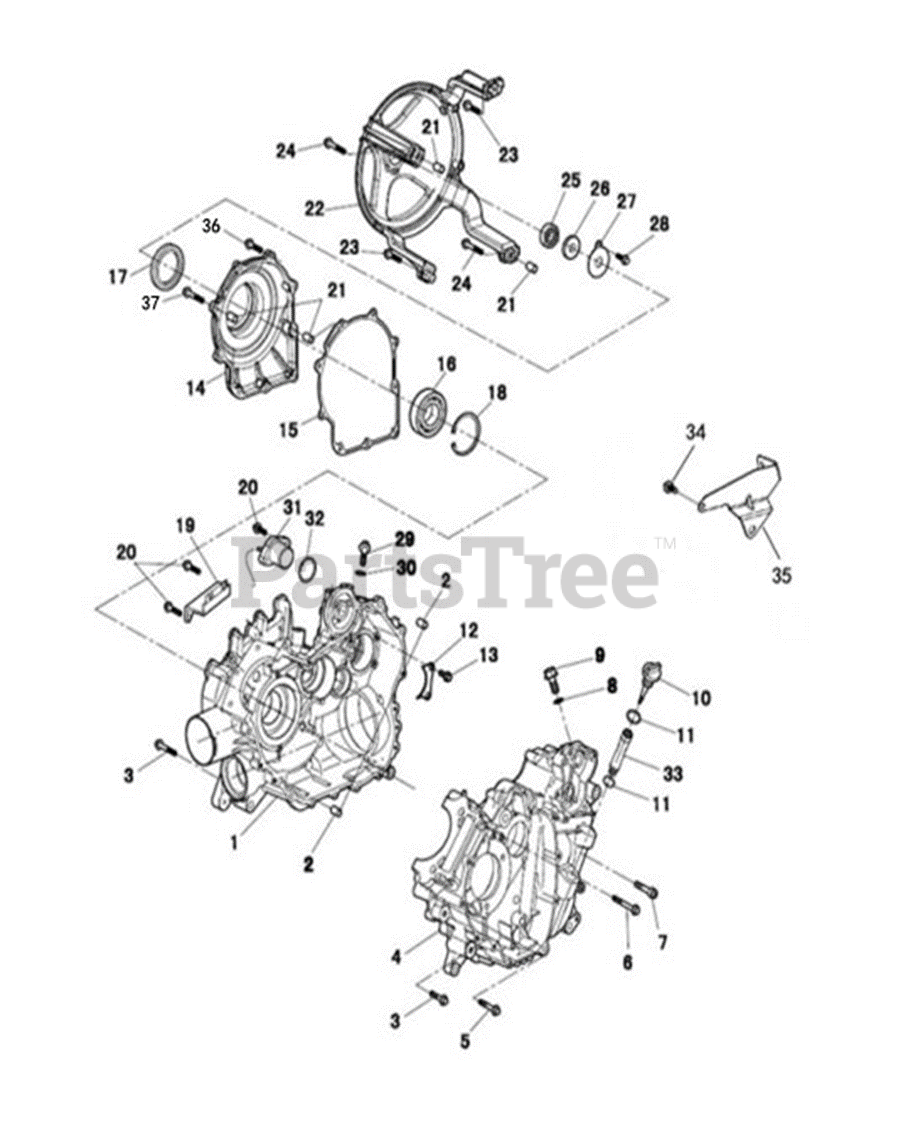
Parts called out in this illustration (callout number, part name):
1	CRANKCASE COVER (RH) (750)
2	DOWEL PIN 9X12X16
3	HEX FLANGE BOLTS M6X30
4	CRANKCASE COVER (LH) (750)
5	HEX FLANGE BOLTS M6X40
6	HEX FLANGE BOLTS M6X85
7	HEX HEAD CAP SCREW M8X40
8	ALUMINUM WASHER 14X20X1.5
9	HEX FLANGE SCREW PLUG M14X1.5X16
10	OIL LEVEL PLUG
11	O-RING 18X3.5
12	MAIN SHAFT BEARING PRESS PLATE
13	HEX FLANGE BOLTS M6X16
14	CLUTCH COVER
15	CLUTCH COVER GASKET
16	BEARING 16010
17	OIL SEAL 35X65X9
19	STRAP-CVT VENT PIPE
20	HEX HEAD BOLT & PLAIN WASHER
21	DOWEL PIN 10X16
22	CLUTCH SHIELD BRACKET
23	HEX FLANGE BOLTS M6X32
24	HEX FLANGE BOLTS M6X40
25	BEARING 62012Z
26	OIL SEAL 12X32X6
27	BRACKET OIL SEAL PRESS PLATE
28	HEX FLANGE BOLT M6X12
29	HEX FLANGE BOLTS M10X1.25X16
30	COPPER WASHER 10X16X1
31	GEAR INDICATOR SENSOR
32	O-RING 29.6X2.4
33	OIL LEVEL GUIDING TUBE
34	HEX FLANGE BOLTS M6X30
35	AIR CLEANER STRAP
36	HEX FLANGE BOLT M6x35
37	HEX FLANGE BOLT M6X45
